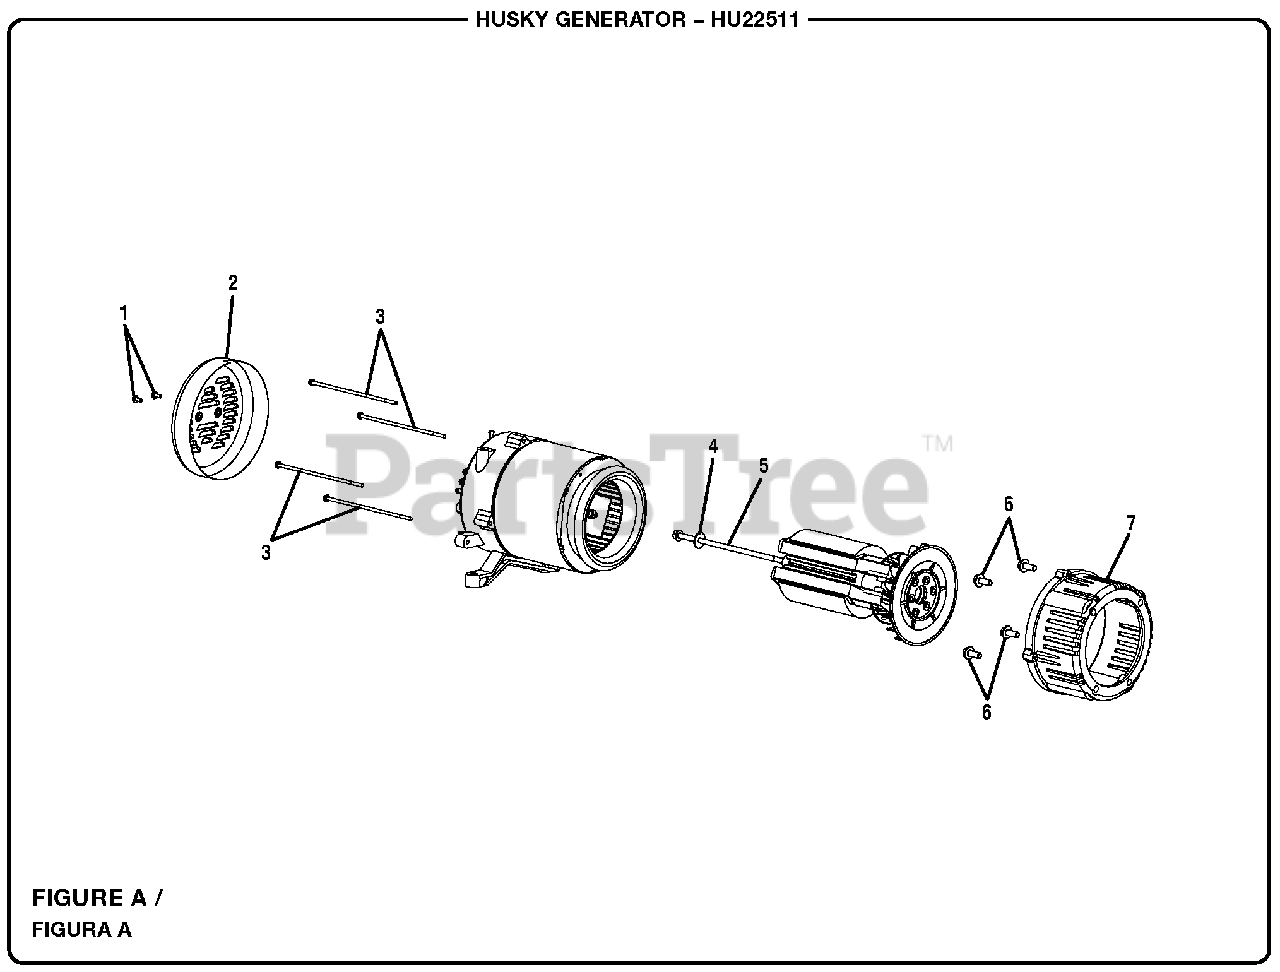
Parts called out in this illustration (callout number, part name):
2	Engine Cover
3	Bolt (1/4-20 x 6 in., Hex Hd.)
4	Lock Washer (5/16 in.)
5	Bolt (5/16-24 x 6-5/8 in., Hex. Hd.)
6	Bolt (3/8-18 x 1-1/4 in.)
7	Engine Adapter
